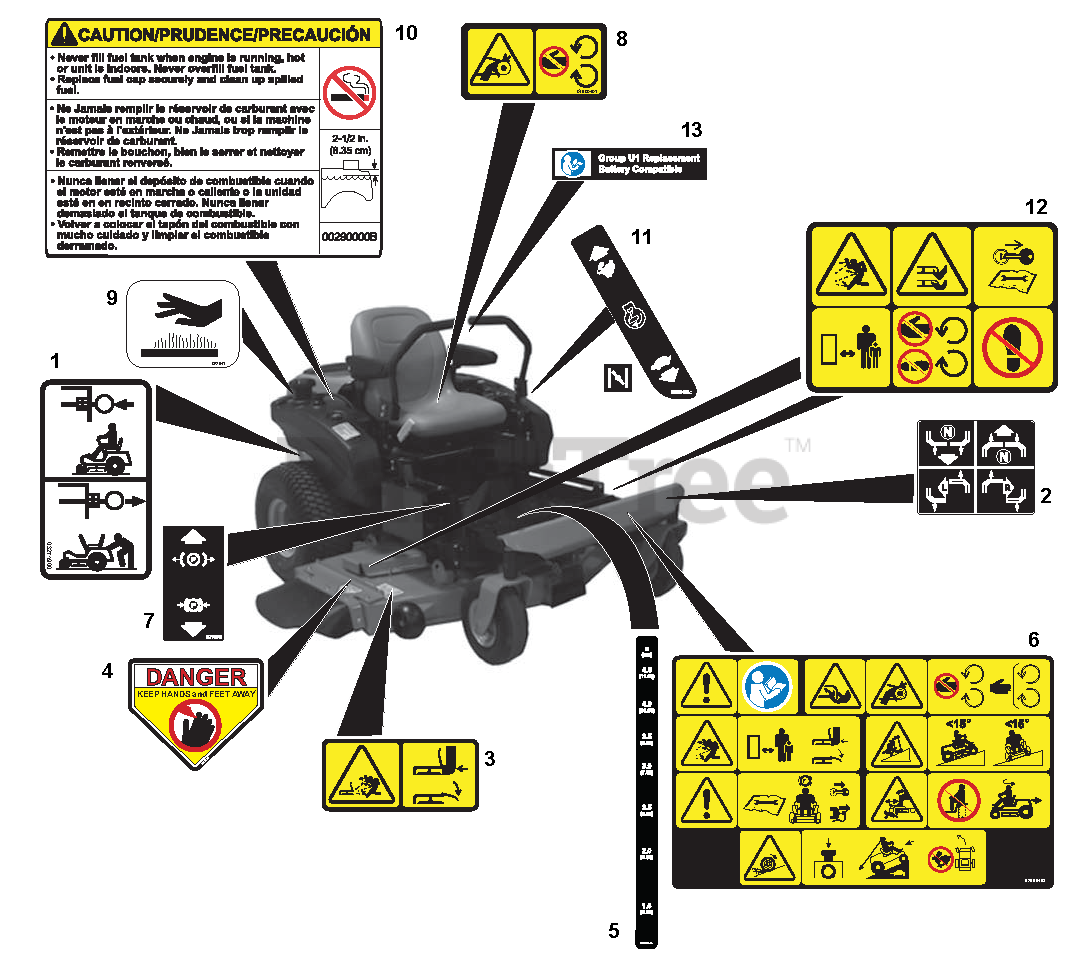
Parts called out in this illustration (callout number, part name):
1	DECAL, TRANSMISSION DISCONNECT
2	DECAL, INSTRUCTIONAL-STEERING
3	DECAL, SAFETY - DECK GUARDING
4	DECAL, DANGER
5	DECAL, CUT HEIGHT XL
6	DECAL, MAIN SAFETY
7	DECAL, PARKING BRAKE LEVER
8	DECAL, SAFETY - GUARDING
9	DECAL, HOT SURFACE
10	DECAL,FUEL WARNING
11	DECAL, SPEED CONTROL
12	DECAL, SAFETY - MOWER DECK
13	DECAL, U1 BATTERY REPLACEMENT
